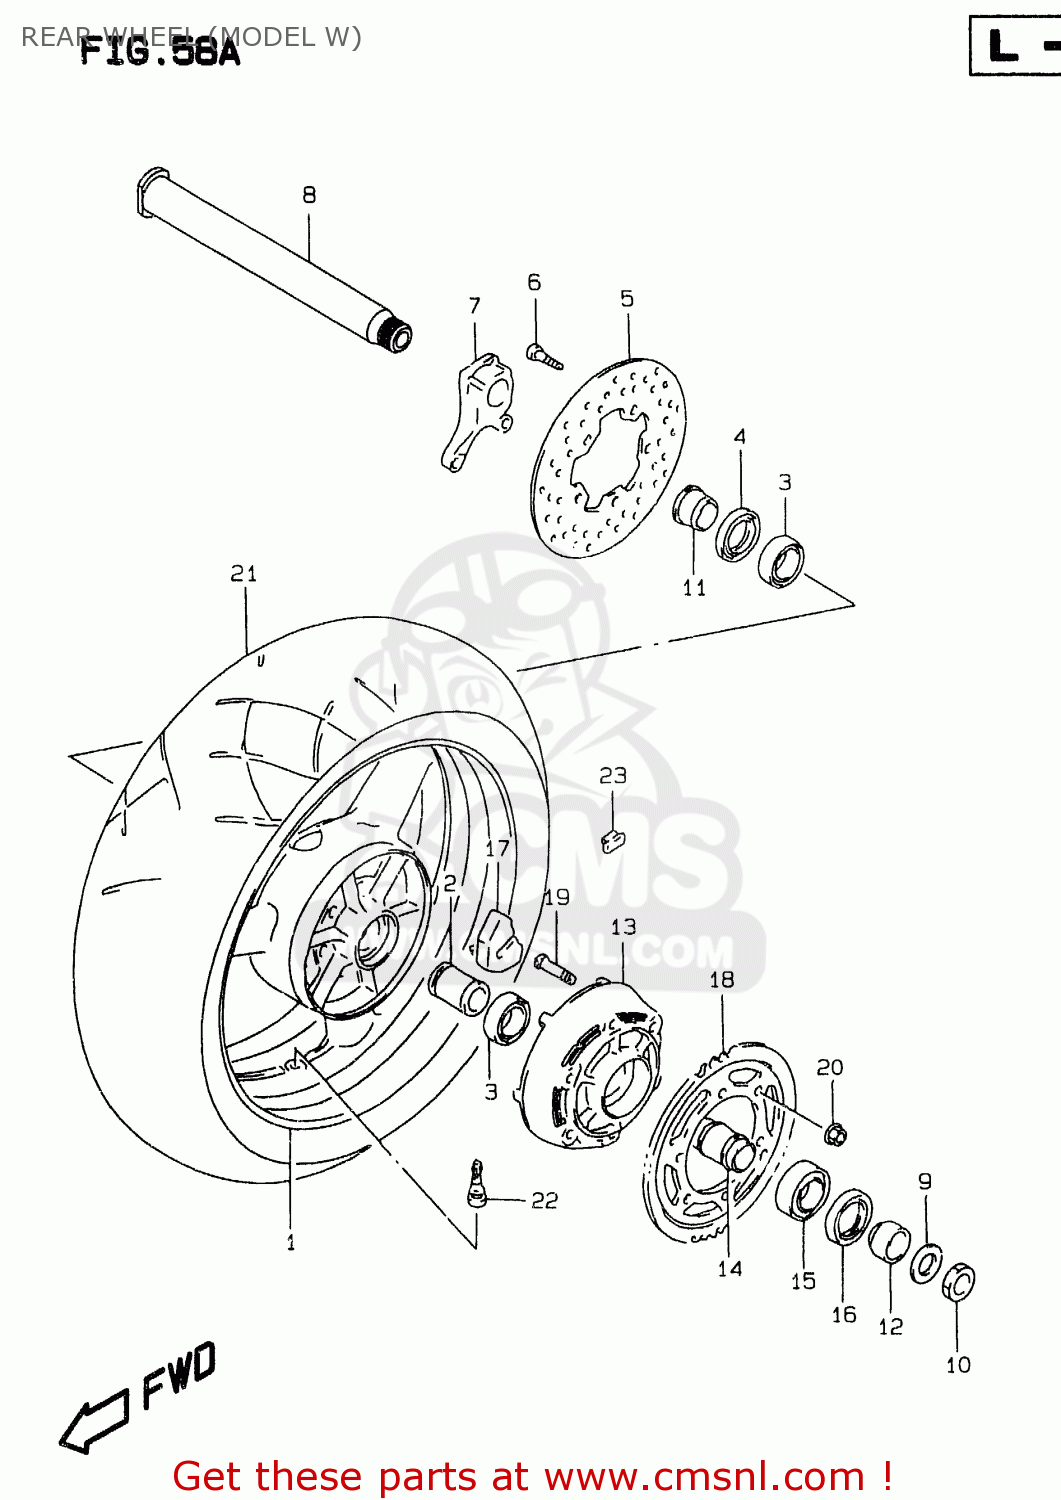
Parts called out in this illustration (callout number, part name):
1	WHEEL,REAR (17XMT6.00)(S
2	SPACER COMP,REAR HUB B
3	BEARING(32X58X13)
4	SEAL,OIL(38X58X7)
5	DISC,RR BRAKE
6	BOLT 8X33
7	BRACKET,RR CALIPER
8	AXLE,RR
9	WASHER(25.2X42X3.2)
10	NUT
11	SPACER,RR AXLE,R
12	SPACER,RR AXLE,L
13	DRUM,REAR SPROCKET MOUNT
14	RETAINER,RR SPROCKET DRUM
15	BEARING
16	SEAL,OIL(39X65X7)
17	ABSORBER,RR HUB SHOCK
18	SPROCKET,RR(NT:44-525)
19	BOLT
20	NUT
21	TIRE,REAR 190/50 ZR17
22	VALVE ASSEMBLY,WHEEL,TR412
23	BALANCER,WHEEL (10G)
